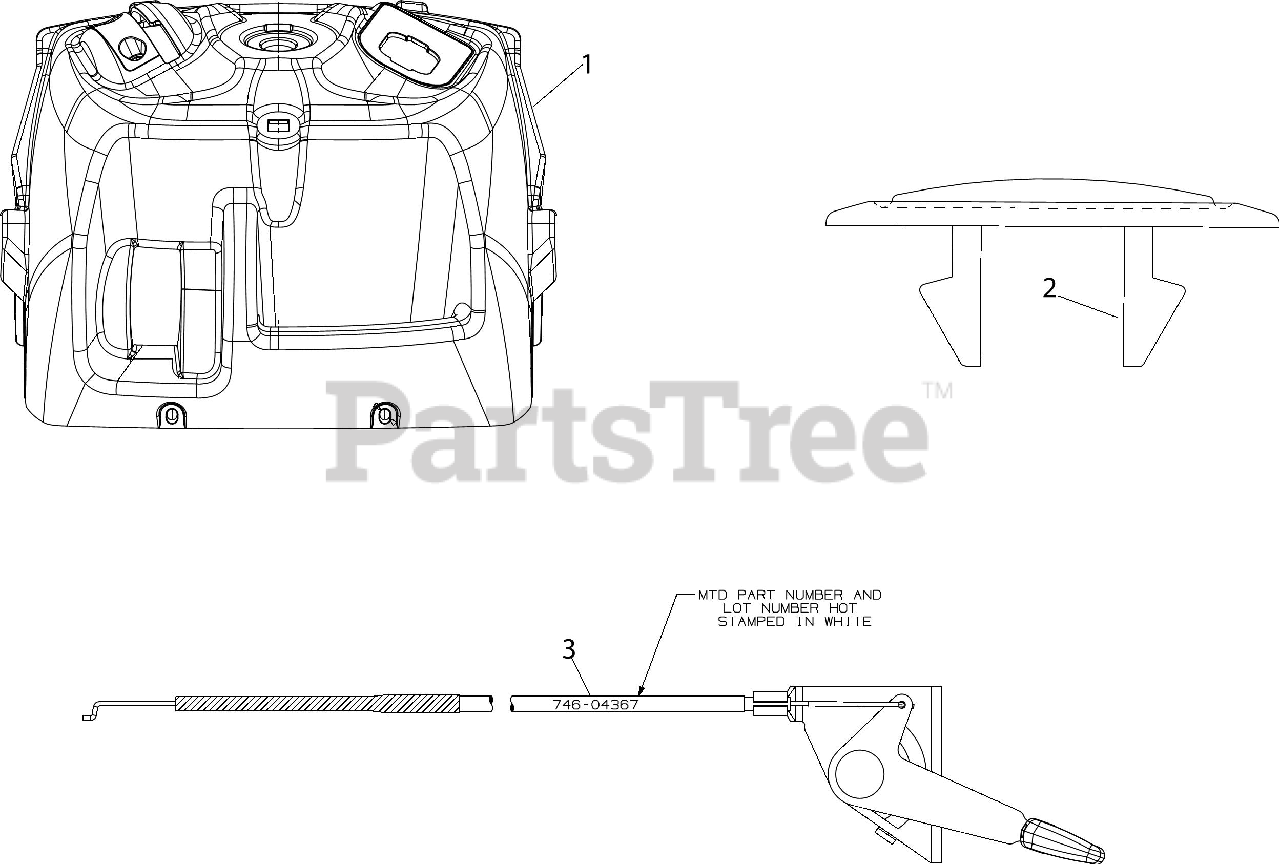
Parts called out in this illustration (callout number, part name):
1	UPPER DASH
2	CHOKE PLUG
3	THROTTLE CABLE 28" x 1.1
